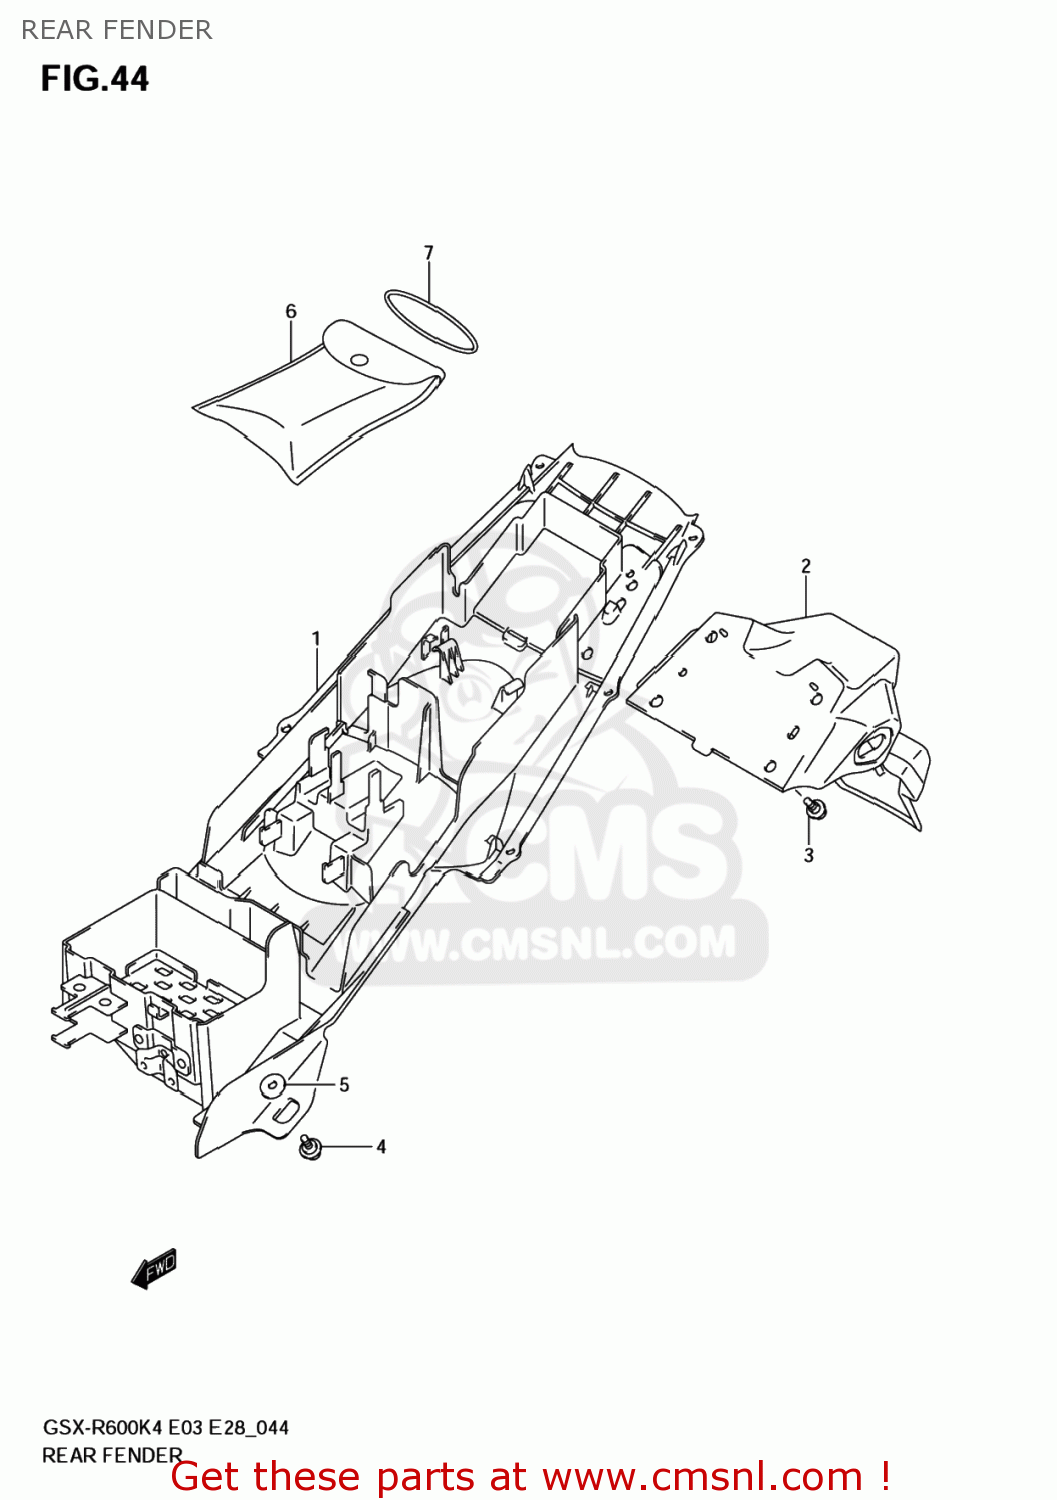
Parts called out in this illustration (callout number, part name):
1	FENDER,RR FR
2	FENDER,RR RR
3	SCREW(6X16)
4	BOLT(6X18)
5	WASHER
6	TOOL ASSY
7	O RING(D:3.5,ID:61)
